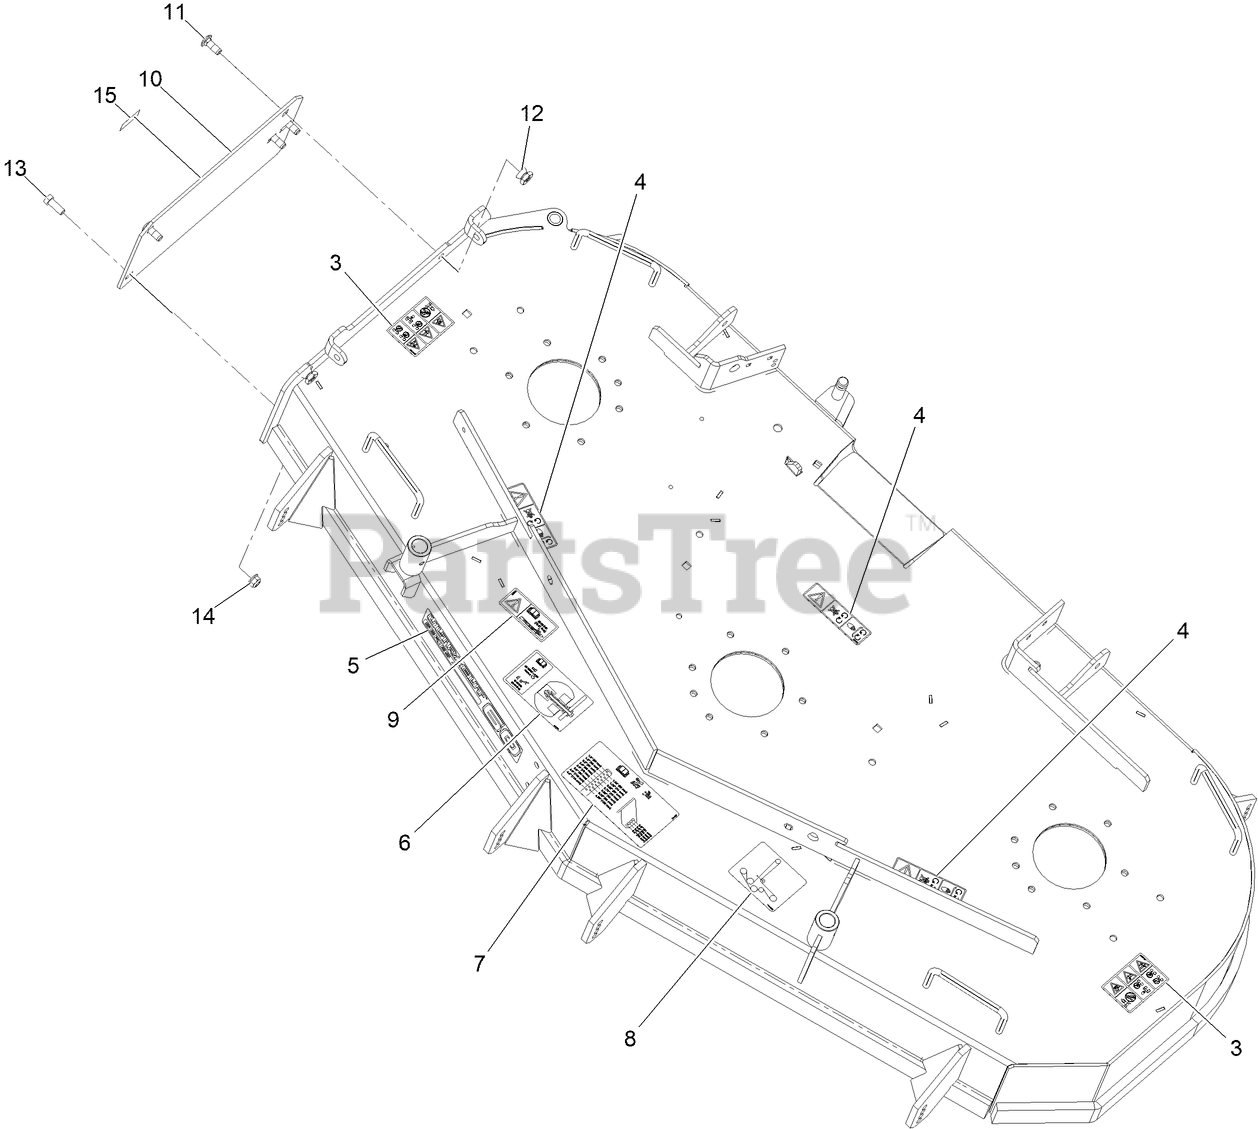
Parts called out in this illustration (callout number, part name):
3	DECAL-WARN THROWN OBJ
4	DECAL-COVER, MISSING
5	DECAL, 604
6	DECAL-ROLLER MOUNTING
7	DECAL-HEIGHT OF CUT
8	DECAL-BELT ROUTING
9	DECAL-TORQUE, BOLT
10	Kit-Discharge Cover
11	SCREW-CARR
12	NUT-BREAKAWAY
13	SCREW-HH
14	NUT-HF, NI
15	Decal-Patent Ttco.Com
